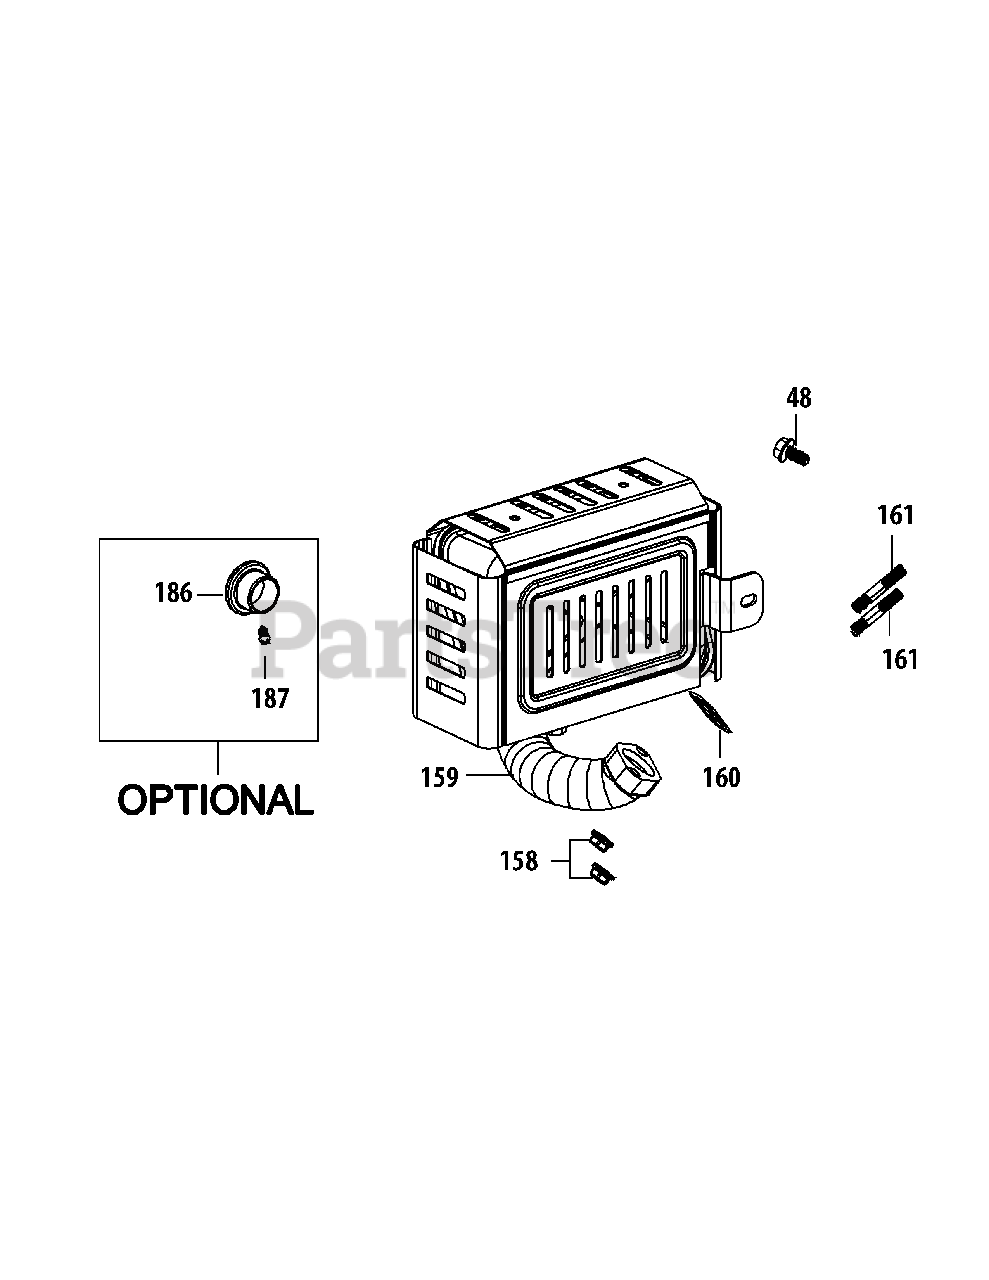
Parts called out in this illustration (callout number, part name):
48	Bolt M6×14
158	Nut M8
159	Muffler Assembly
160	Exhaust Pipe Muffler Gasket
161	Muff Stud M8×47
161	Muffler Stud Assembly
186	Spark Arrestor
187	Spark Arrestor Screw
